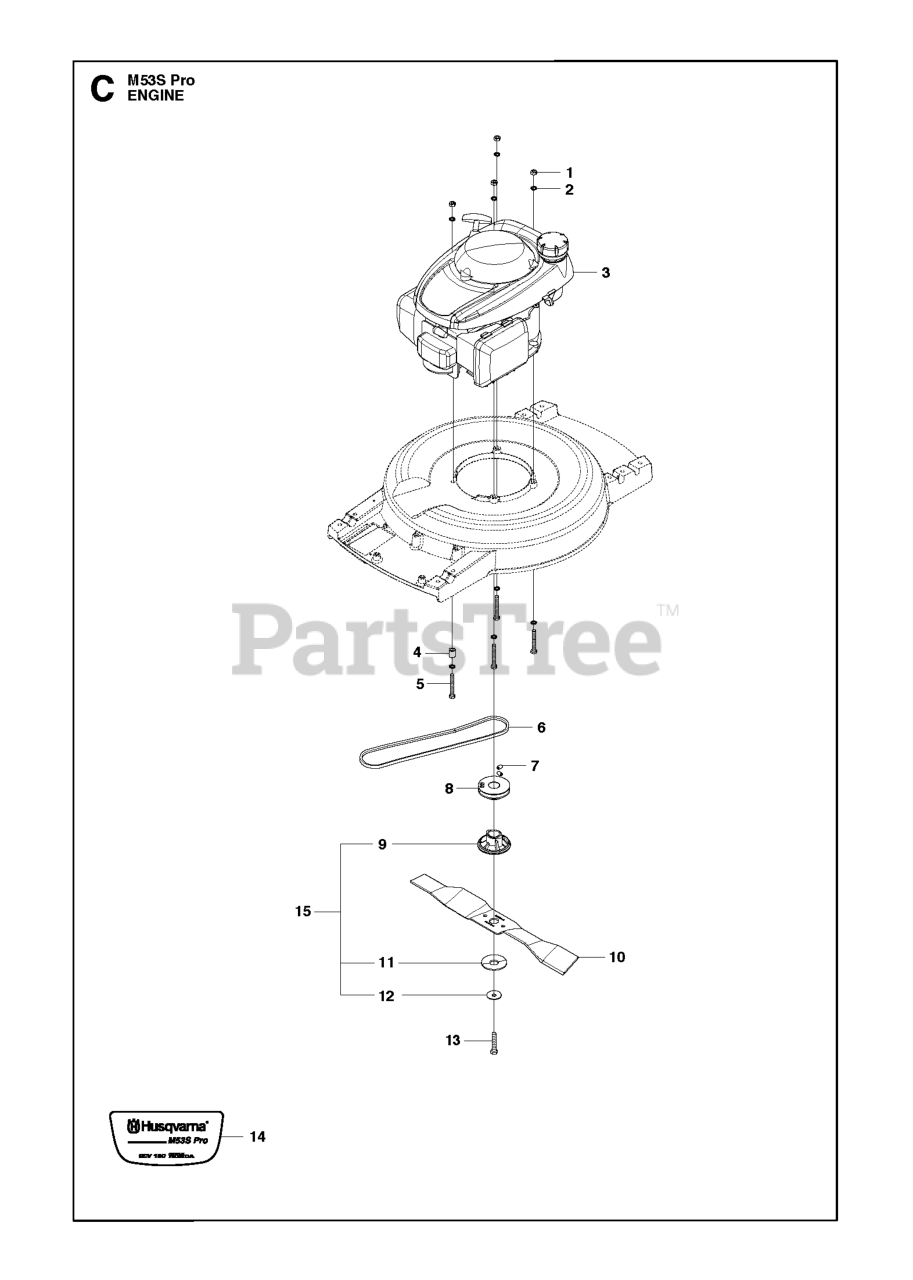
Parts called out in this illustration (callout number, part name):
1	NUT
4	SPACER M53 / M48
6	BELT
8	PULLEY M53S / M48S
9	BLADE SUPPORT
11	SPRING M53 / M48
13	BOLT M53 / M48
